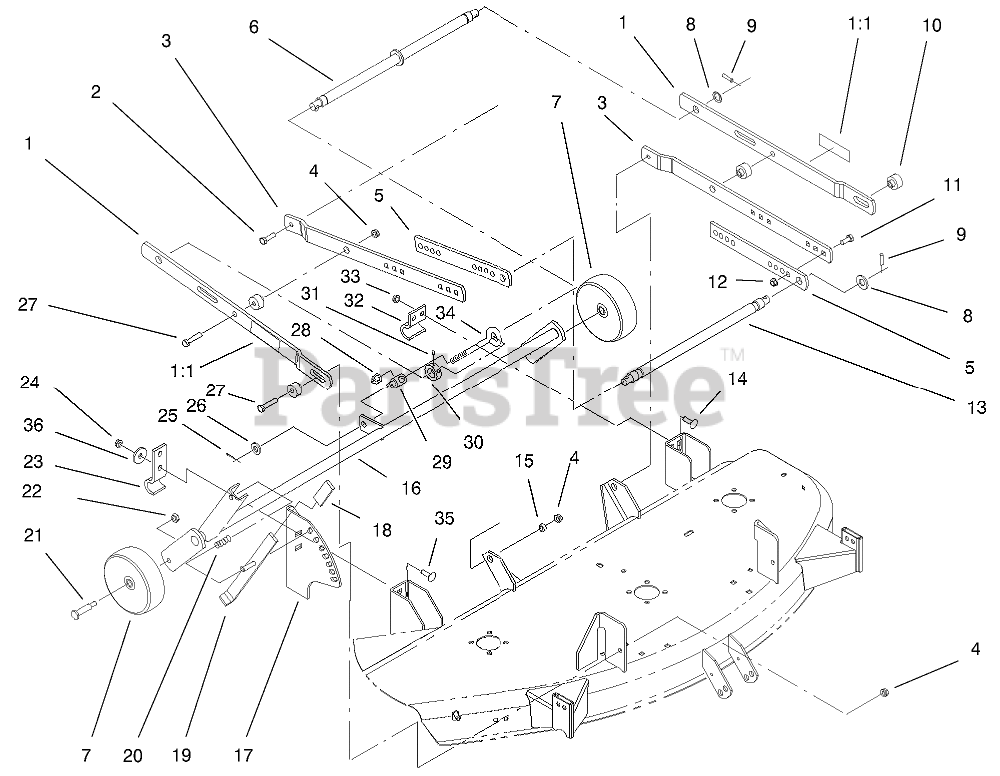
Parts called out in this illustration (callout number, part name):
1	RH LEVELER ASM
1	LH LEVELER ASM
1	Bar-Leveler
1:1	DECAL-WARNING
2	SCREW-HH
3	DRAFTBAR
4	LOCKNUT-FLANGE
5	DRAFTBAR-ADJUSTMENT
6	SHAFT-LEVELER
7	WHEEL
8	WASHER-FLAT
9	PIN-ROLL, SPIROL
10	SPACER
11	SCREW-CARR
12	NUT-LOCK, CONE
13	SHAFT-DRAFTBAR
14	BOLT-CARR
15	SPACER
16	SUPPORT-WHEEL
17	QUAD-DECK
19	LEVER-HOC
20	SPRING-COMPRESSION
21	BOLT-SHOULDER
22	NUT-HEX
23	BRACKET-PIVOT
24	NUT-LOCK, NI
25	PIN-COTTER
26	WASHER-FLAT
27	SCREW-HH
28	NUT-LOCK, NI
29	TRUNNION
30	COLLAR
31	SCREW-SET, HSH
33	NUT-FLANGE
34	ROD-ADJUSTMENT, LEVEL
35	SCREW-CARR
36	WASHER-SUPPORT
